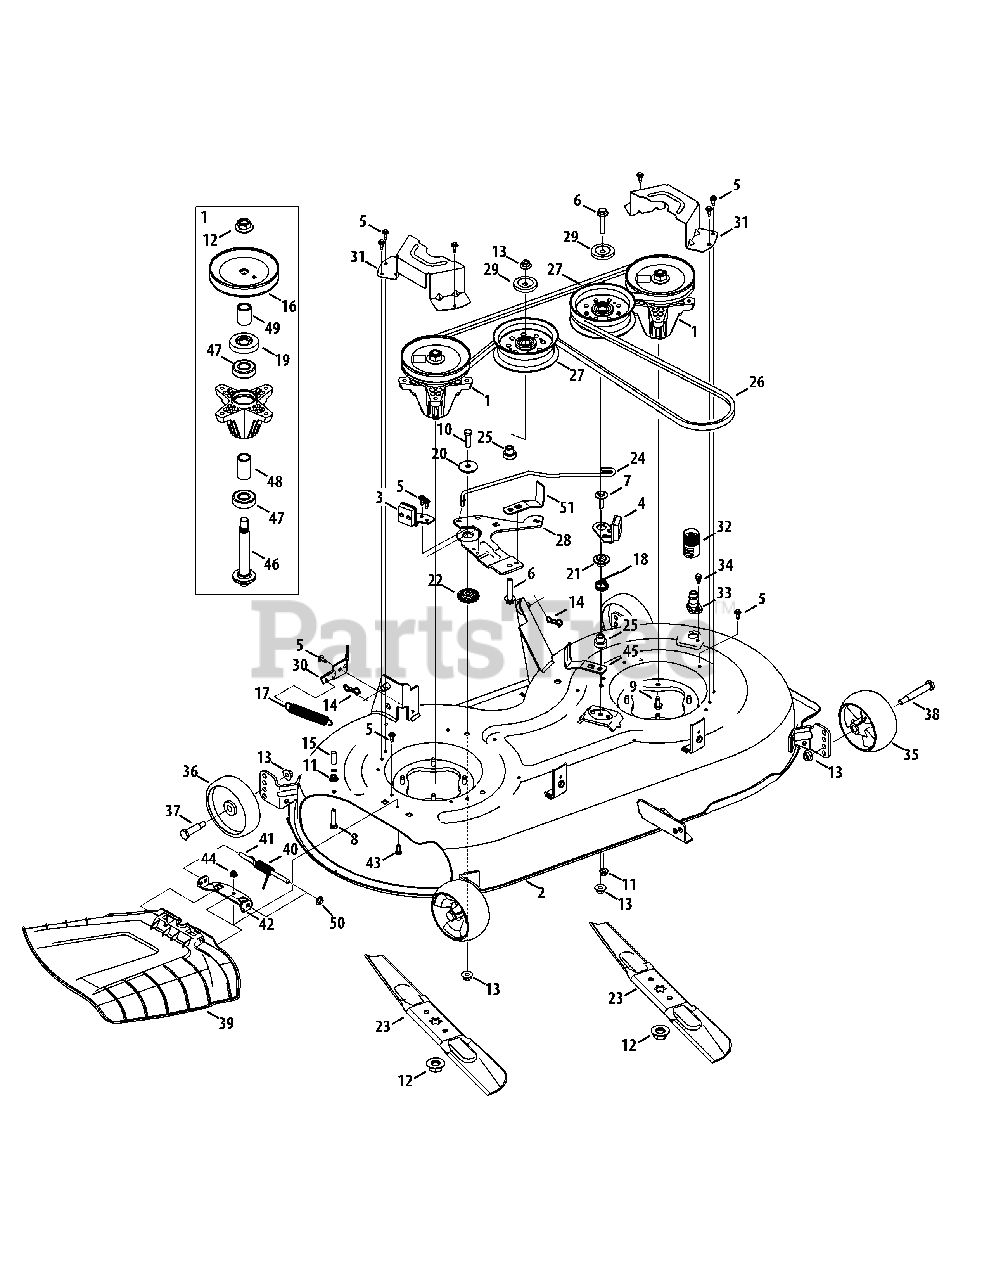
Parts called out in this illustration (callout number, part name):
1	Spindle Ass’y, Pulley, 6.3 Dia
2	Deck, 42"
3	Brake Assembly, Deck, RH
4	Brake Assembly, Deck, LH
5	Screw, M6-1 x .625
6	Hex Cap Screw, 3/8-16 x 2.00
7	Hex Cap Screw, 5/16-18 x 1.25
8	Hex Cap Screw, 5/16-18 x 1.00
9	Screw, Self-tapping, 5/16-18, 0.750,
10	Hex Cap Screw, 3/8-16 x 1.25
11	Nut, Flange Lock, 5/16-18, Nylon
12	Nut, Flange, 5/8-18
13	Flange Lock Nut, 3/8-16
14	Bow-Tie Cotter Pin
15	Vinyl Cap, .29 x .50
16	Pulley, Deck, 5.40 Dia.
17	Spring, Extension, .750 x .477
18	Spring, Torsion, LH Brake
19	Bearing Shield
20	Flat Washer, .39 x 1.5 x .134
21	Shoulder Spacer, .75 x .145
22	Shoulder Spacer, .854 x .191
23	Blade, Cut, 21.23" 2-In-1
24	Rod, Brake, Deck
25	Shoulder Spacer, Idler
26	Belt, V-Type, A Sec x 99.75
27	Pulley, Idler, 4.50" Dia.
28	Idler Bracket
29	Pulley Cap
30	Bracket, Cable, PTO
31	Belt Cover
32	Coupler, Water
33	Deck Wash Nozzle
34	Shoulder Screw, 1/4-20 x 0.50
35	Wheel, Deck, 5.0 Dia. Ball
36	Wheel, Deck 5.0 x 1.38
37	Bolt, Shoulder, .496 x 1.525, 3/8-16
38	Bolt, Shoulder, .496 x 2.50, 3/8-16
39	Chute Deflector Assembly
40	Spring, Torsion, .440 ID x 1.75
41	Hinge Pin
43	Hex Cap Screw, 1/4-20 x .62
44	Nut, Flange Lock, 1/4-20, Nylon
45	Belt Keeper
46	Shaft, Spindle, 5.75
47	Bearing, Ball, .787id x 1.85 Od x .551
48	Spacer, .792 x 1.060 x 1.860
49	Spacer, .800 x 1.10 x 1.470
50	Push Cap
